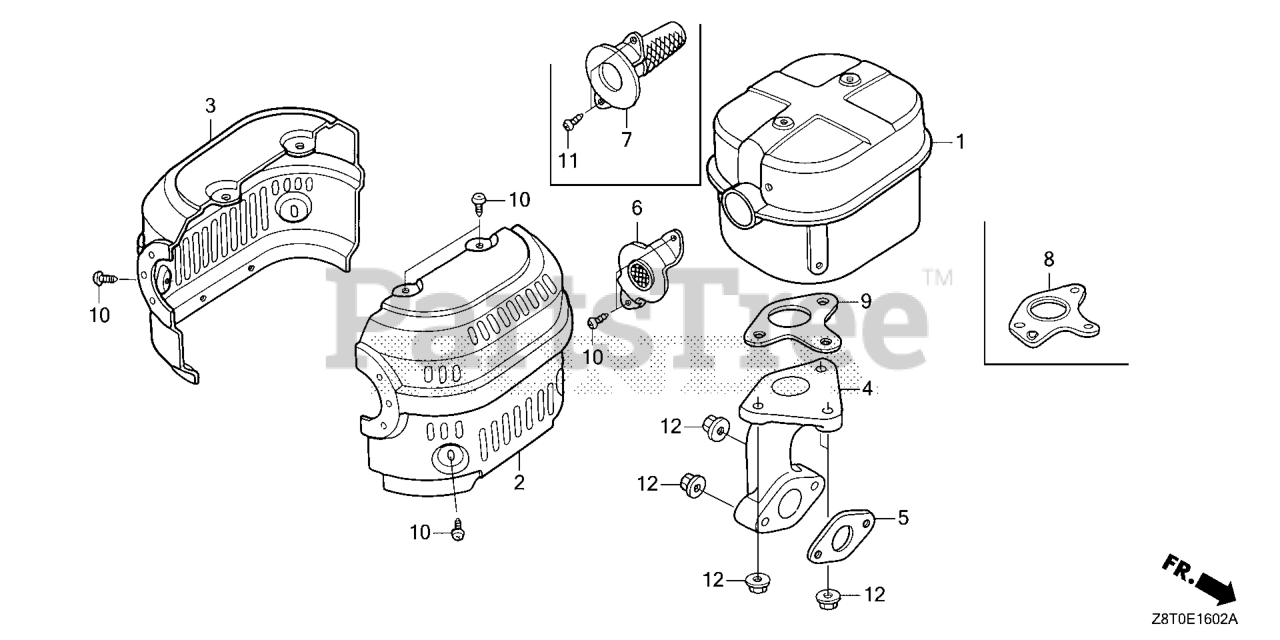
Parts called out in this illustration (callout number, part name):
2	PROTECTOR, R. MUFFLER (ALUMINIZED)
3	PROTECTOR, L. MUFFLER (ALUMINIZED)
4	PIPE, EX.
5	GASKET, EX. PIPE
6	FLANGE, BAFFLE
7	ARRESTER, SPARK
9	GASKET, MUFFLER (THAI LEAKLESS)
10	SCREW, TAPPING (5X8)
11	SCREW, TAPPING (5X8)
12	NUT, FLANGE (8MM)
